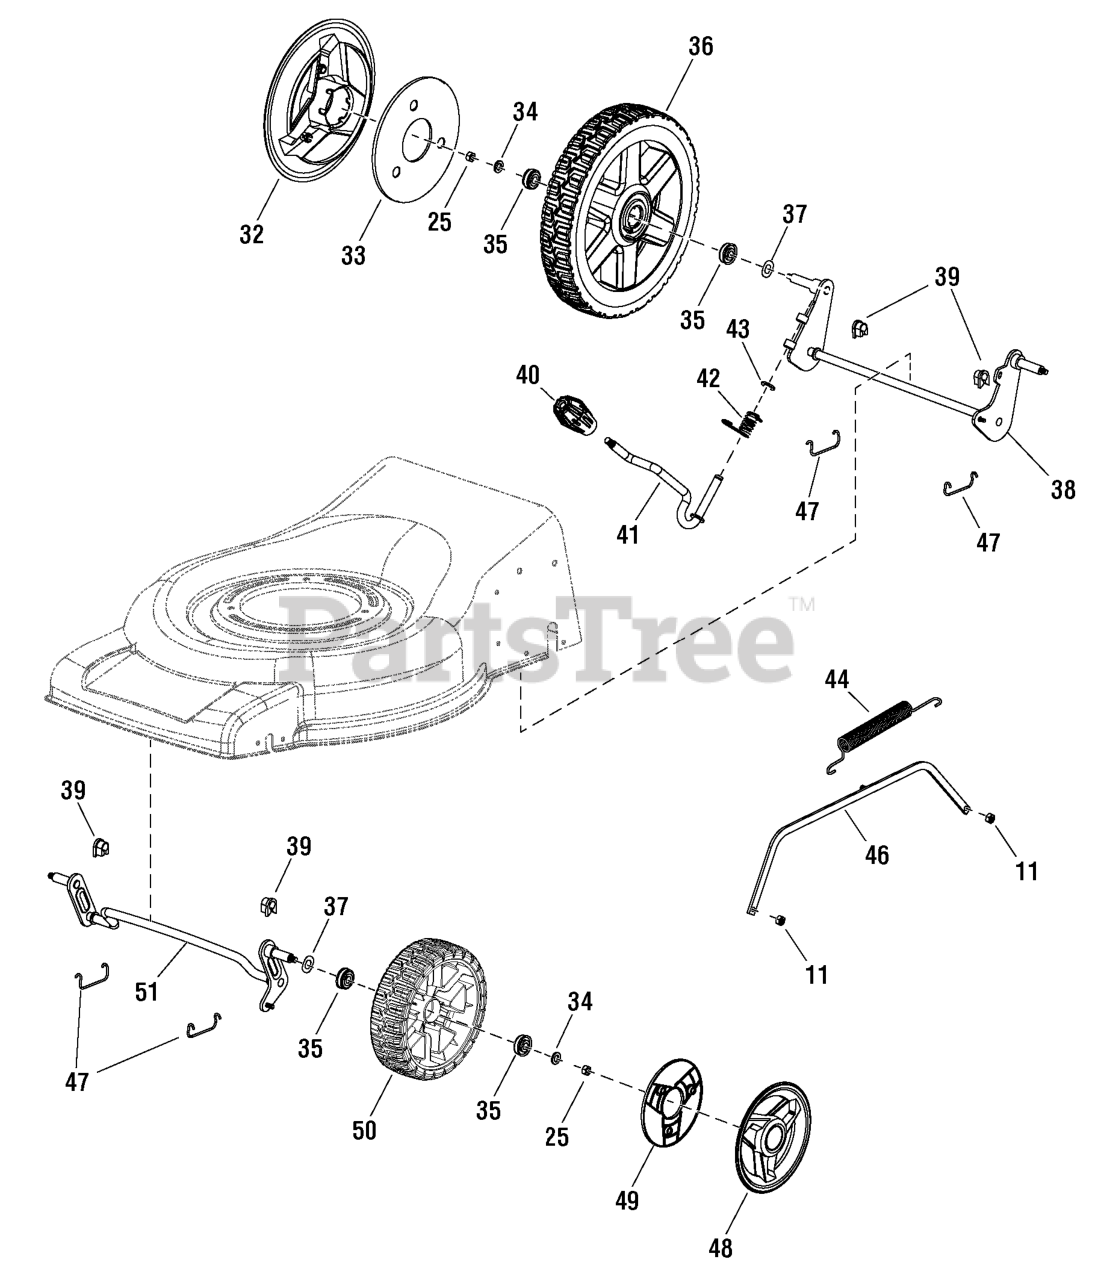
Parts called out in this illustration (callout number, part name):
11	NUT, M6
25	NUT, Hex, M8
32	HUBCAP
33	DUST COVER
34	WASHER, Plain, 8
35	BEARING
36	WHEEL, Rear
37	WASHER, Wave
38	AXLE ASSEMBLY, Rear
39	BUSHING
40	KNOB, Height Adjust
41	LEVER, Height Adjust
42	SRPING, Height Adjust
43	WASHER, Split, 8
44	SPRING, Connecting Rod
46	CONNECTING ROD
47	CLIP, Axle
48	HUBCAP
49	DUST COVER
50	WHEEL, Front
51	AXLE ASSEMBLY, Front
